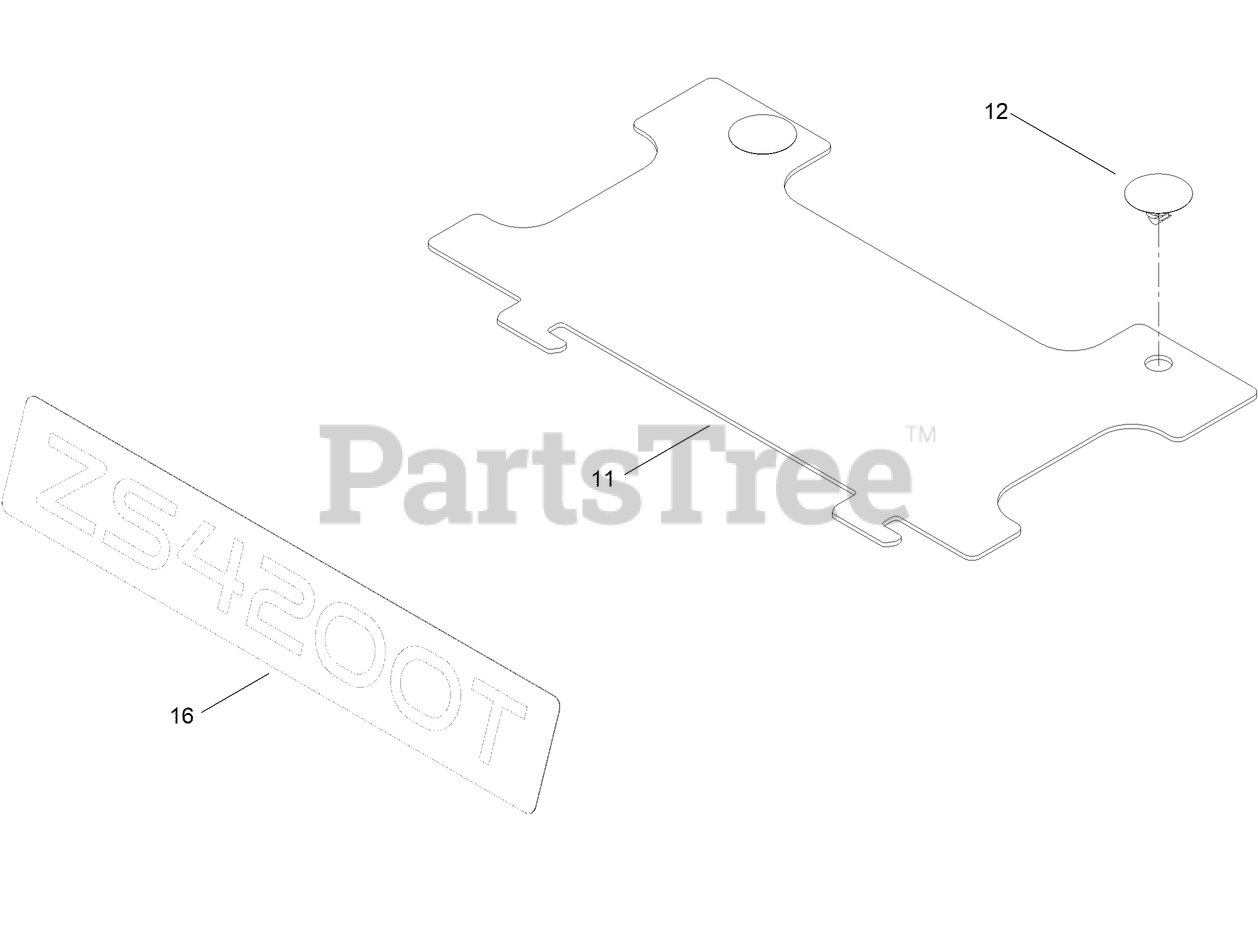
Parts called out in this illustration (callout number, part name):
11	SHIELD
12	RIVET-PLASTIC
16	DECAL ZS4200T
